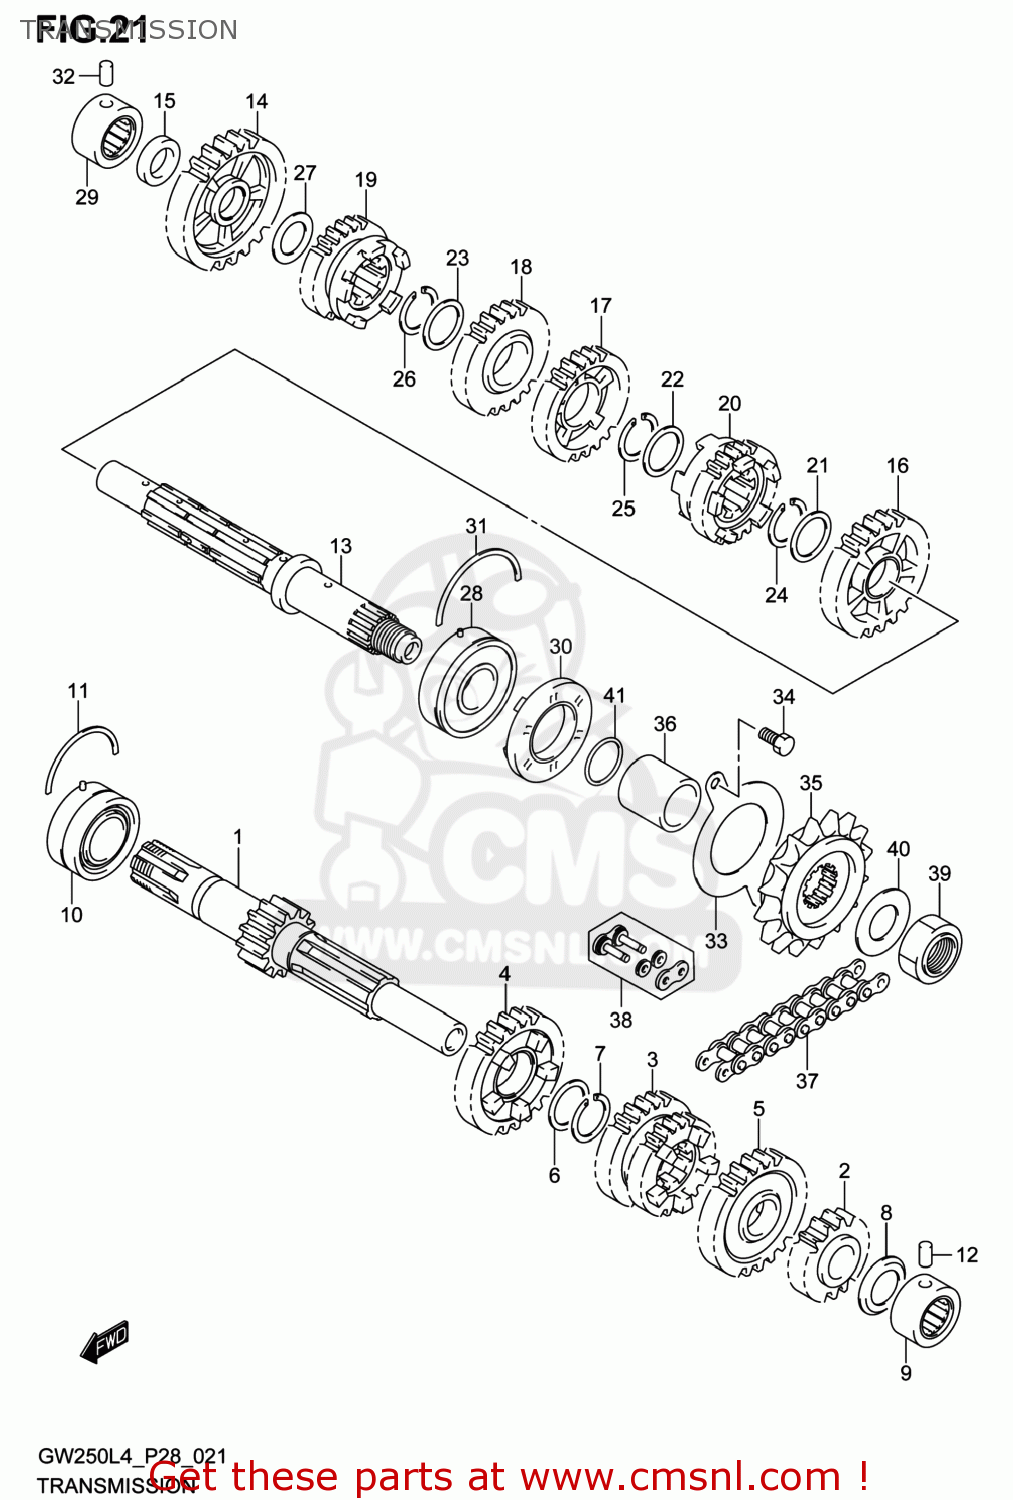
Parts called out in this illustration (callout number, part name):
1	SHAFT,COUNTER
2	GEAR,2ND DRIVE
3	GEAR,3RD & 4TH DRIVE
4	GEAR,5TH DRIVE
5	GEAR,6TH DRIVE
6	SHIM(22X28X1)
7	CIRCLIP
8	SEAL,COUNTER SHAFT,L BEARING
9	BEARING(17X30X16)
10	BEARING(22X47X20.6)
11	C RING
12	PIN
13	SHAFT,DRIVE
14	GEAR,1ST DRIVEN
15	SPACER,1ST DRIVEN GEAR
16	GEAR,2ND DRIVEN
17	GEAR,3RD DRIVEN
18	GEAR,4TH DRIVEN
19	GEAR,5TH DRIVEN
20	GEAR,6TH DRIVEN
21	SHIM(22X28X1)
22	SHIM(22X28X1)
23	SHIM(22X28X1)
24	CIRCLIP
25	CIRCLIP
26	CIRCLIP
27	WASHER
28	BEARING(22X56X16)
29	BEARING(17X30X16)
30	SEAL,OIL(30X56X9.5)
31	C RING
32	PIN
33	RETAINER,DRIVE SHAFT OIL SEAL
34	BOLT
35	SPROCKET,ENGINE
36	SPACER,ENGINE SPROCKET
37	CHAIN,DRIVE(DID 520VF)
38	JOINT SET,CHAIN
39	NUT
40	SHIM(22X36X1)
41	O RING(D:2.5,ID:21)
